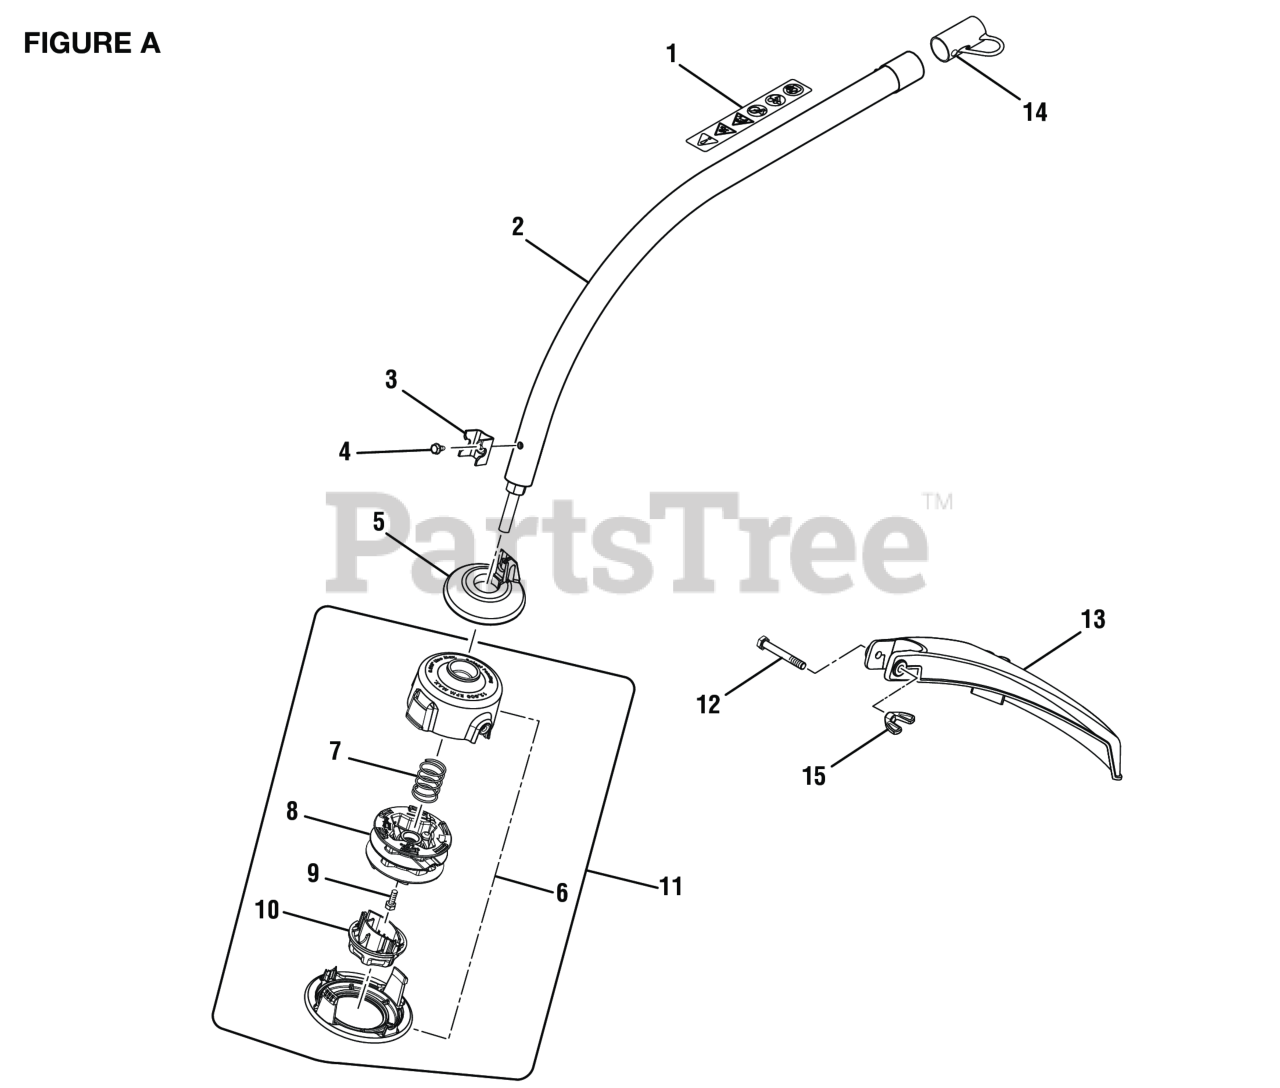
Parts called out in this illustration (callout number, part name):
1	Warning Icon Label
2	Curved Shaft Assembly
4	Screw (#10-32 x 3/8 in., Hex Washer Hd. S.T.)
5	Grass Shield
6	Stringhead Housing
7	Compression Spring
8	Spool Assembly
9	Bolt (5/16-18 x 1/2 in.)
10	Bump Knob
11	Trimmer Head Assembly (.095)
12	Bolt (1/4-20 x 45 mm, Cap Hex Hd.)
13	Grass Deflector Assembly
14	Hanger Cap
15	Wing Nut (1/4-20, Plastic)
